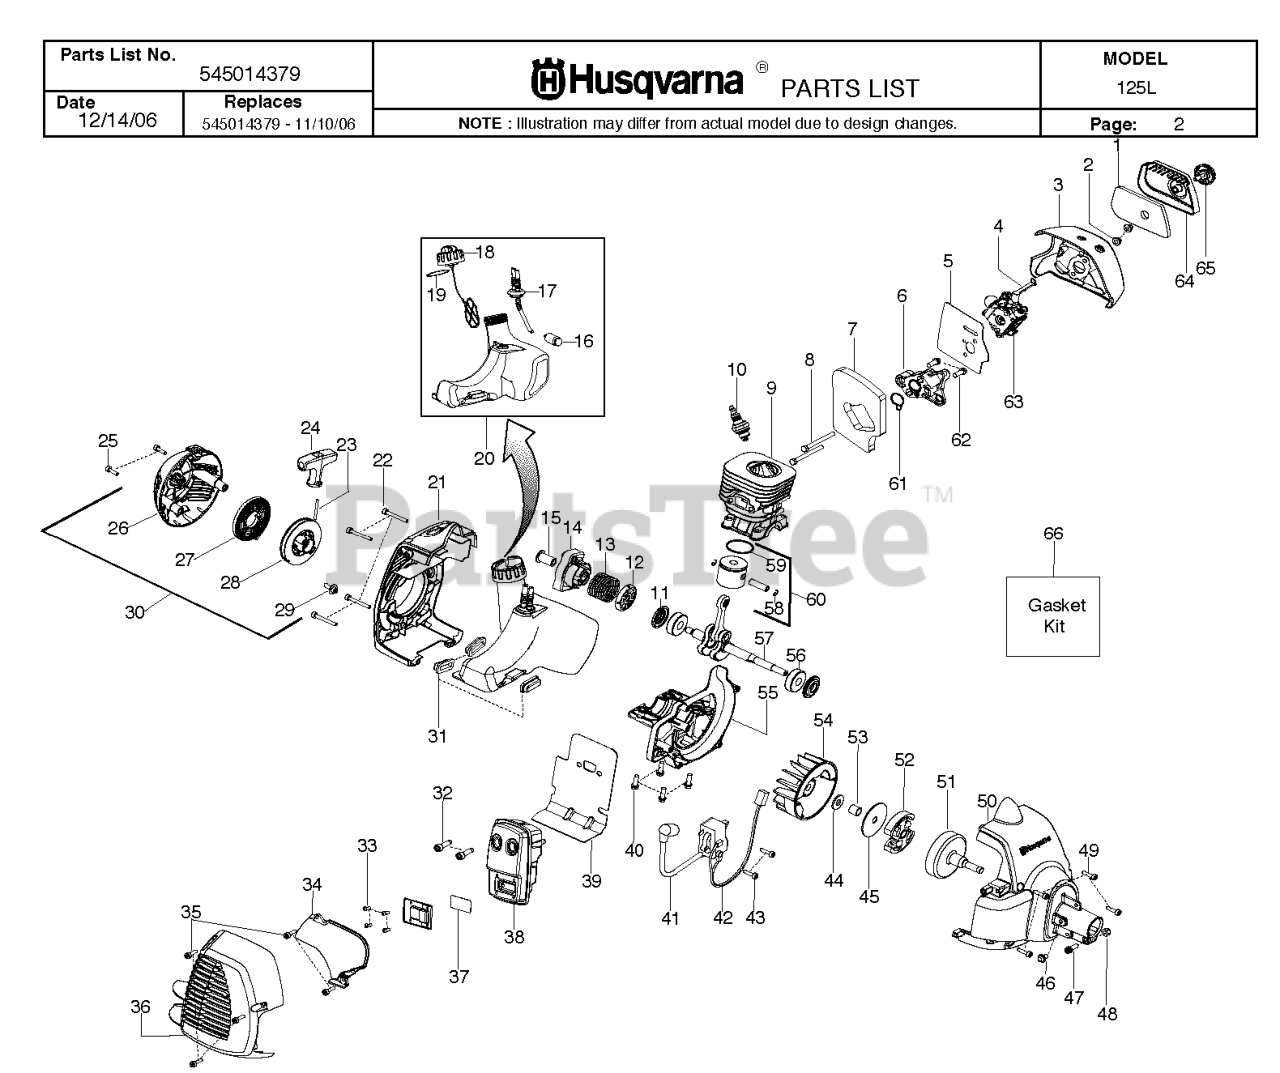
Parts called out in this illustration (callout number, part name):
1	FILTER AIRBOX
3	Air Box
4	CHOKE LEVER
5	KIT GASKET CARB
6	CARB ADAPTOR
7	KIT GASKET 28CC TRIMMER
8	BOLT CARB ADAPTOR
9	CYLINDER
10	Plug-Spark
11	KIT SEAL CRANKSHAFT
12	WASHER STARTER
13	SPRING STARTER CUP
14	ASSY-STARTER CUP
15	COUPLING STARTER
16	FUEL PICK-UP ASSY
17	KIT FUEL LINE
18	ASSY-CAP W/RETAINER
19	O RING NITRILE
20	%FUEL TANK ASSY
21	REAR SHROUD
24	STARTER HANDLE GRAY
25	SCREW M5-0.8X30MM
26	STARTER HOUSING
27	%KIT STARTER SPRING
28	KIT STARTER PULLEY
30	ASSY-STARTER HSG.
31	ISOLATOR FUEL TANK
32	BOLT MUFFLER
33	SCREW-10-16 X 1/2 HI-LO
34	SHIELD HEAT
35	SCREW M4 X 1.75 PT 16MM
36	GUARD-MUFFLER
37	KIT SPARK ARRESTOR SCREEN
38	ASSY MUFFLER NC
39	GASKET PAPER METAL
40	SCREW-M5-0.8 X 25MM(TAP)
41	IGNITION MODULE MBU-7
42	ASSY MODULE LEAD WIRE
43	SCREW M4 X .70 TT 16MM
45	WASHER-CLUTCH
48	NUT HEX LOCK 10-24
49	SCREW M4 X .70 TT 16MM
50	FAN HSG ASSY
51	Assy-Clutch Drum
52	%KIT CLUTCH ASSY
53	SPACER FLYWHEEL
55	CRANKCASE CASTING
56	BEARING RADIAL BALL (6201)
57	KIT CRANKSHAFT ASSY
58	WRIST PIN RET.
59	RING PISTON
60	KIT PISTON 28CC TRIMMER
61	KIT GASKET 28CC TRIMMER
62	SCREW-M5-0.8 X 25MM(TAP)
63	KIT CARBURETOR
64	COVER-AIR BOX
65	KNOB ASSY AIRBOX COVER
66	KIT GASKET 28CC TRIMMER
